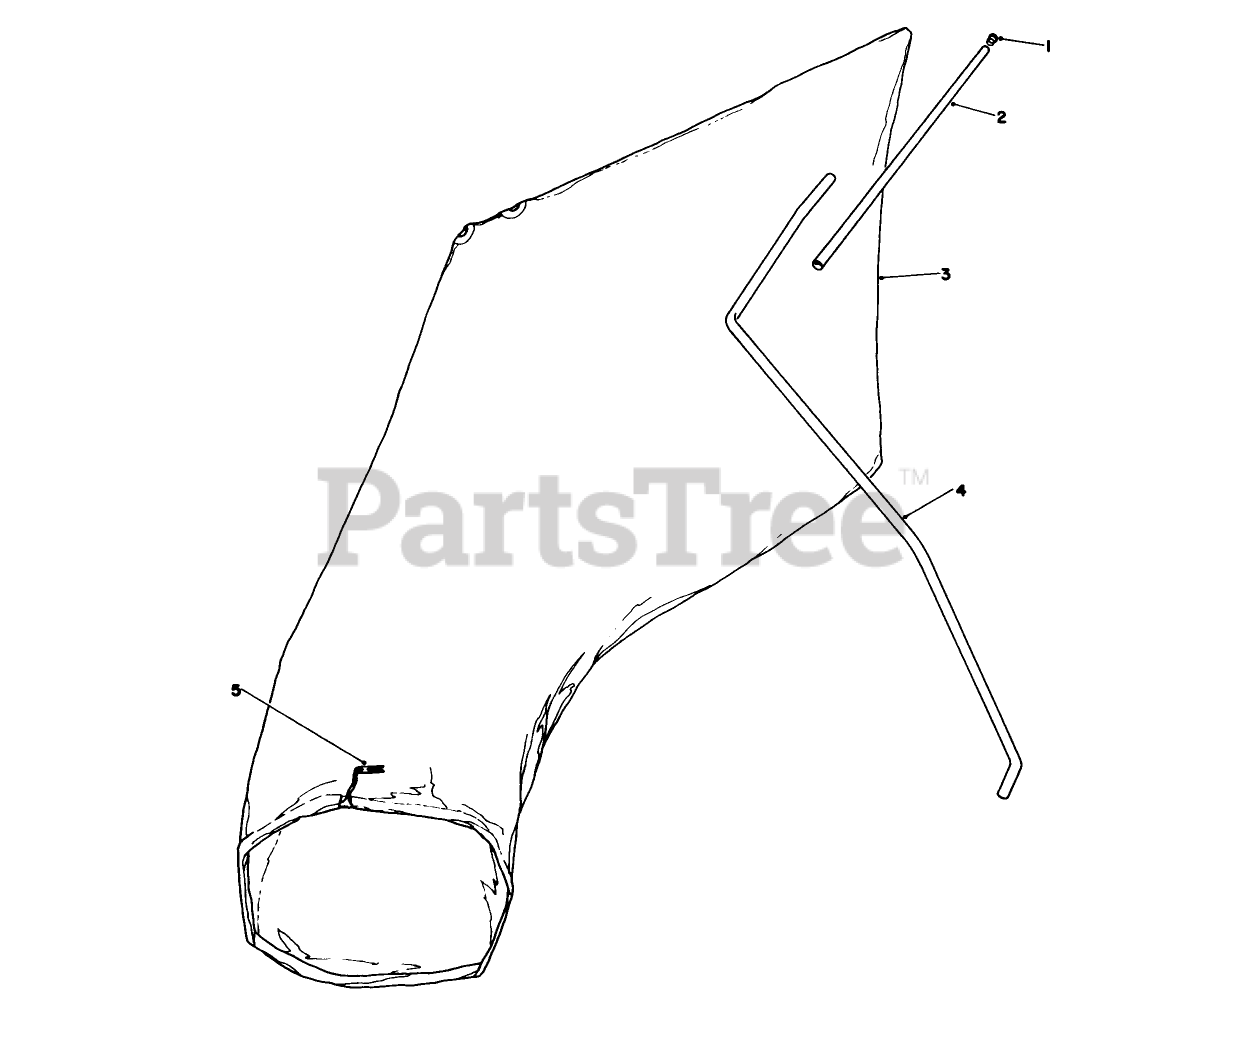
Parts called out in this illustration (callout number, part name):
2	BAG HANGER TUBE
3	Bag (Incl. Ref. #5)
4	HANGER ROD
5	BAG CORD FASTENER
